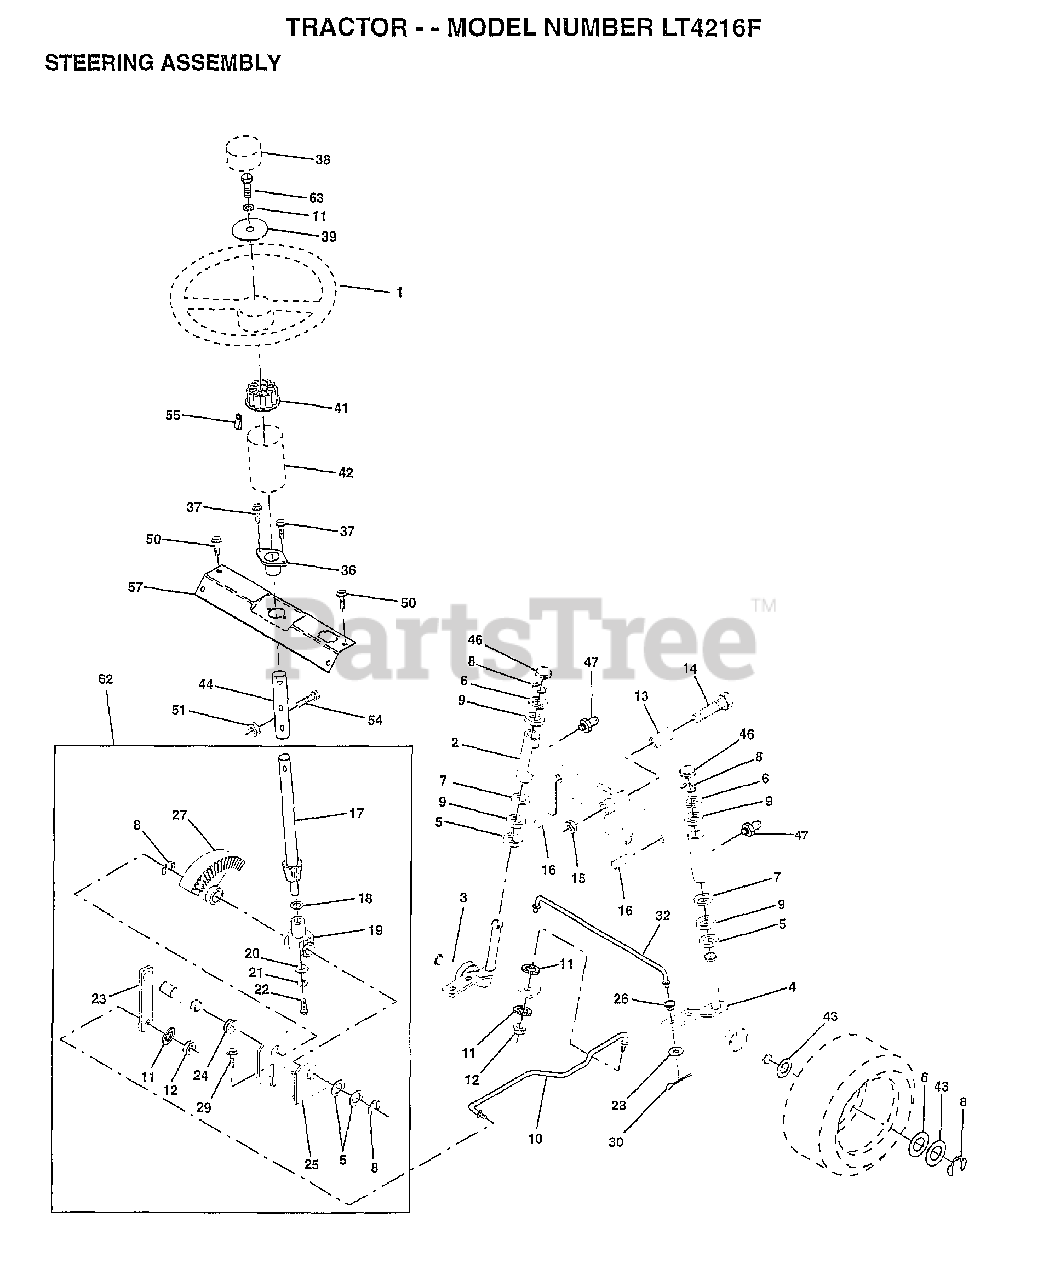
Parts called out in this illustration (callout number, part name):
1	WHEEL STR AYP BLK
2	AXLE ASM FRONT
3	SPINDLE LH
4	SPINDLE RH
5	WASHER .T
6	WASHER
7	WASHER
8	RING
9	COL. SRTG. BEAR.
11	LOCKWASHER
13	BEARING
14	BOLT HEX 5/8-11
15	"NUT-LOC,FLANGE LT"
16	AXLE PIN
17	SHAFT ASM STEERIN
18	THRUST WASHER
19	SUPPORT.SHAFT
21	LOCKWASHER
22	SCREW.SCKTHD.CAP
24	NYLINER T
25	"BRKT,STEERING"
26	BUSHING.DRAGLINK
27	GEAR SECTOR
28	WASHER
29	SCREW
30	COTTER PIN
32	TIE ROD
38	CAP STEER AYP
39	WASHER T
41	ADAPTER LT
42	BOOT SHAFT STEER
43	WASHER
44	SHAFT EXT STEERIN
46	CAP
47	ZERK M
50	SCREW HEX CRT
51	NUT
54	BOLT
55	CLIP TINNERMAN
57	SUPPORT SHAFT STR
63	BOLT
